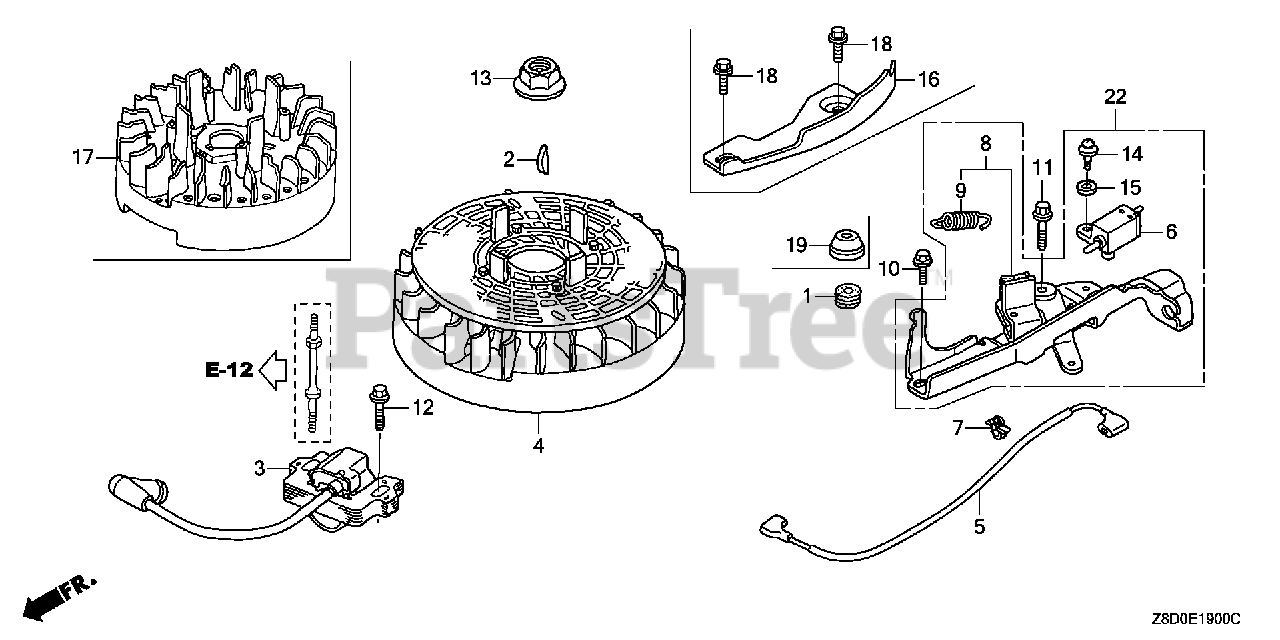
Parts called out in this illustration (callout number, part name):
2	KEY, SPECIAL WOODRUFF (25X18)
3	COIL ASSY., IGNITION (USE FOR F/W OF TEC) (TEC)
4	FLYWHEEL ASSY. (TEC) (USE FOR IGN. COIL OF TEC)
5	WIRE, STOP SWITCH
6	SWITCH ASSY., ENGINE STOP (N.C)
7	HOLDER, WIRE (FASTEX)
7	CLIP A, CABLE (3.8MM BLACK) (NIFCO)
8	BRAKE ASSY.
9	SPRING, BRAKE LEVER
10	BOLT, FLANGE (6X14) (CT200)
11	BOLT, FLANGE (6X23) (CT200)
12	BOLT, FLANGE (6X23) (CT200)
13	NUT, FLANGE (14MM)
14	SCREW-WASHER (4X12)
15	WASHER, PLAIN (4MM)
22	BRAKE ASSY.
